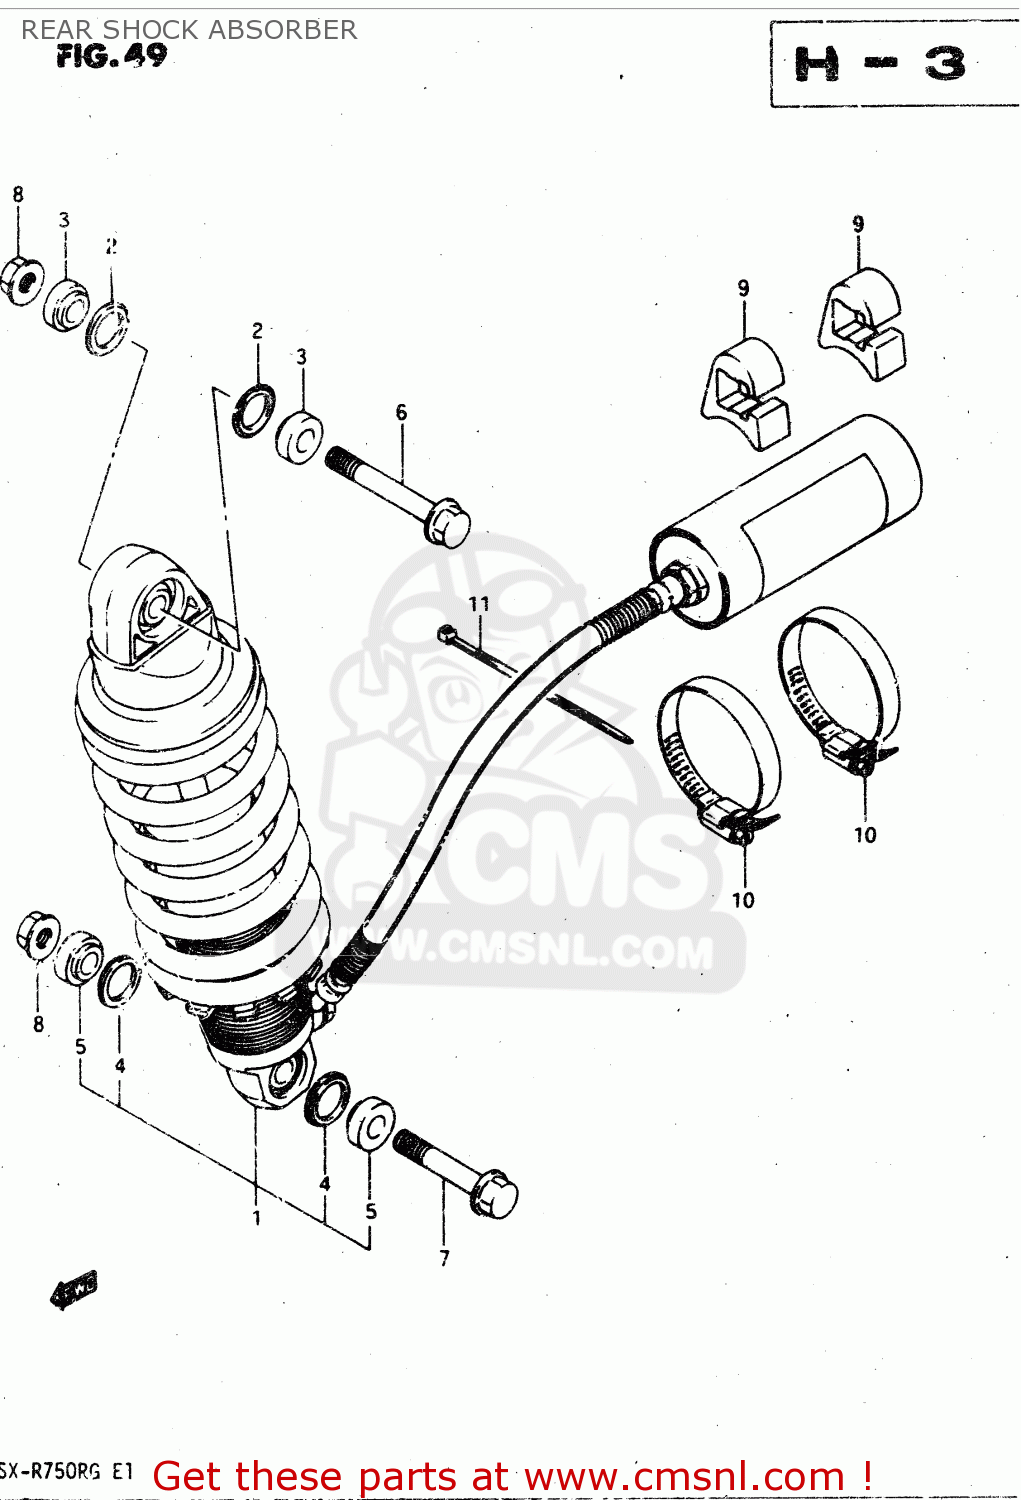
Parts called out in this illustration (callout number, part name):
1	ABSORBER ASSY,RR SHOCK
2	SEAL DUST
3	COLLAR
4	SEAL,DUST RR SHOCK ABSORBER
5	COLLAR
6	BOLT
7	BOLT(10X48)
8	NUT
9	CUSHION,RESERVOIR TANK
10	CLAMP
11	CLAMP(L:145)
